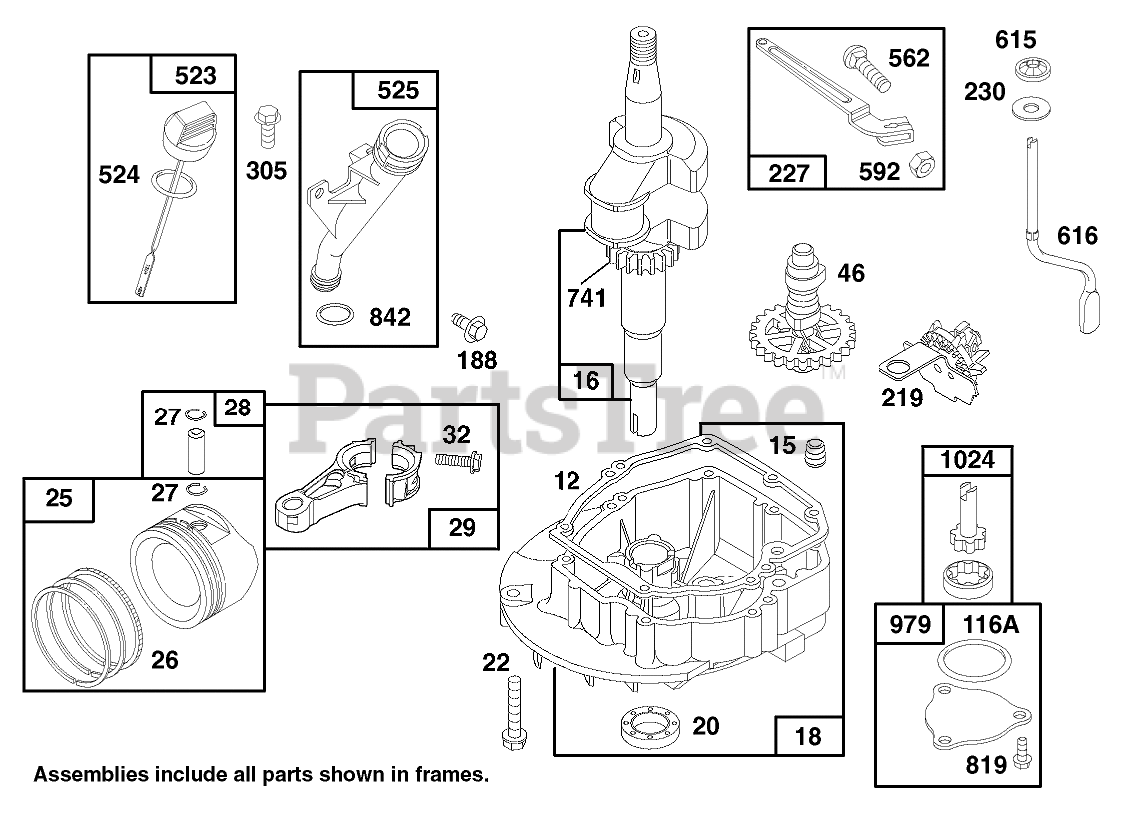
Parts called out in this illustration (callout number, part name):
12	ENGINE BASE GASKET
15	PIPE PLUG
16	CRANKSHAFT
18	ENGINE SUMP
20	SEAL-OIL
22	SCREW - ENGINE BASE
25	STD PISTON ASSEMBLY
26	STD RING SET
27	PISTON PIN LOCK
28	PIN ASM - PISTON
29	CONNECTING ROD
32	Connecting Rod
46	CAM GEAR
116A	O RING SEAL
188	Screw-Cap
219	GOVERNOR/OIL SLINGER
227	GOVERNOR LEVER ASSEMBLY
230	WASHER
305	SCREW - HEX HEAD
523	DIPSTICK-OIL
524	O-RING
525	OIL FILLER TUBE
562	GOVERNOR LEVER BOLT
592	HEX NUT
615	FASTENER
616	GOVERNOR CRANK
741	TIMING GEAR
819	SCREW - SEM
842	O-RING
979	OIL PUMP COVER
1024	OIL PUMP
